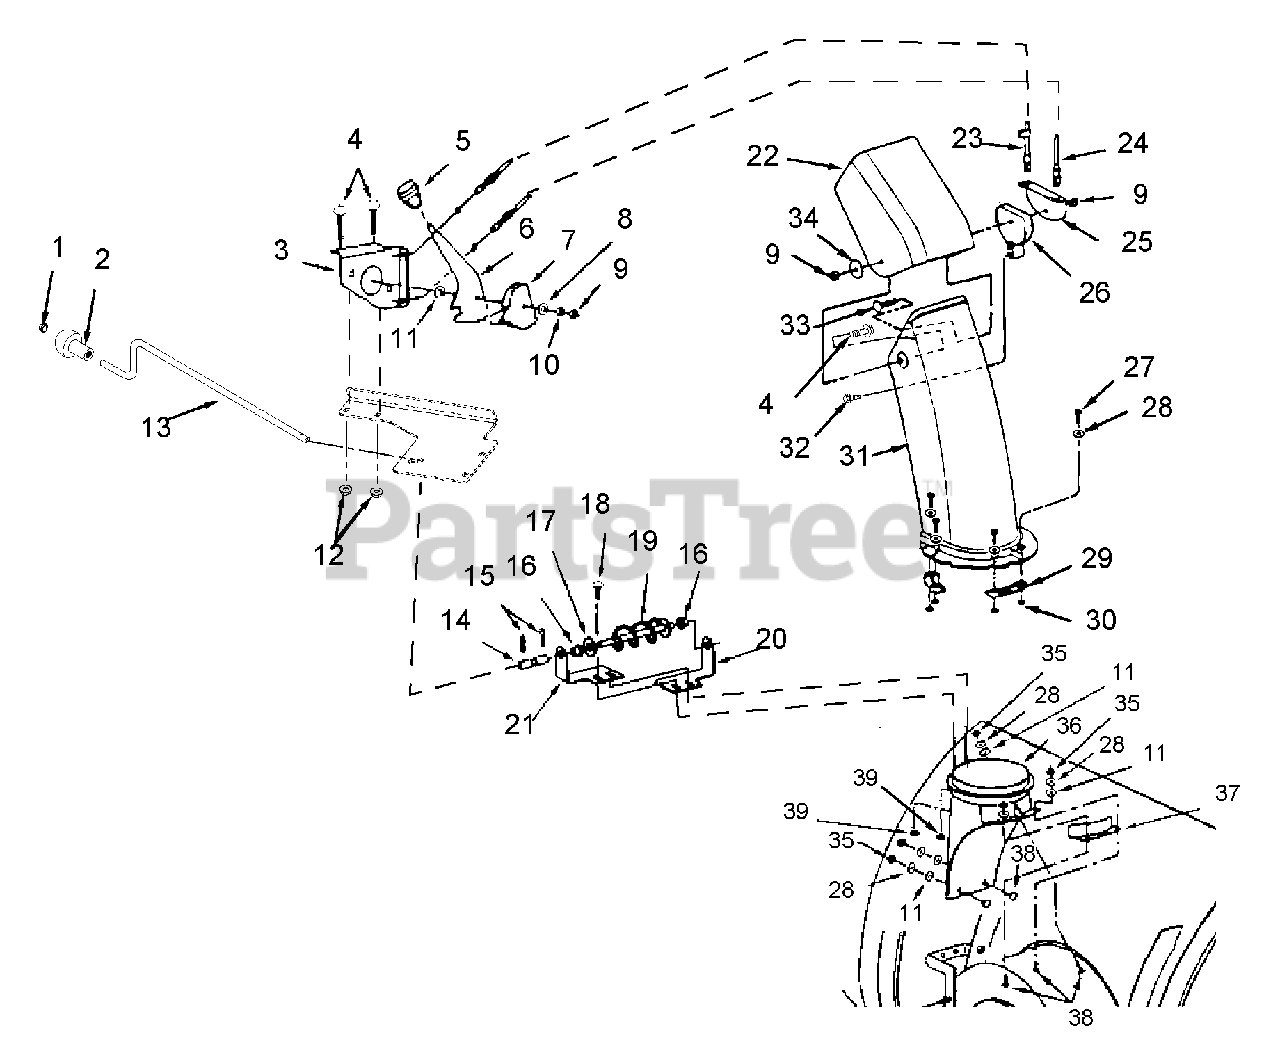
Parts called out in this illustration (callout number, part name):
1	CAP, 3/8 ROD YWZC
2	KNOB
3	Assembly, Chute Tilt Bracket
4	@BLT-RDHDSQNK .31-18X.75 G5YZ
5	Knob
6	Handle, Chute Tilt
7	Guide, Cable
8	@WSHR-FL-STL.344X.688X.065YWZC
9	@NUT-LK-CTR .31-18 YWZC
10	@WSHR-LK .31X.078 REG YWZC
11	WSHR-FL-NY .375X.75X.060
12	@NUT-LK-TOP-FLG .31-18 YWZC
13	CRANK, CHUTE
14	UNIVERSAL JOINT ASS'Y
15	PIN, SPRING CLIP
16	BUSHING,3/8" (AGRI-FAB)
17	@WSHR-FL-STL.406X.812X.065 YWZ
18	@BLT-RDHDSQNK .31-18X1.00 G5YZ
19	WORM,CHUTE CRANK
20	BKT,CHUTE CRANK FRONT
21	BKT,CHUTE CRANK REAR
22	Chute, Upper
23	Cable, Chute Control with Clip
24	Cable, Chute Control
25	Bracket, Cable
26	Guide, Cable
27	@BLT-HEX .25-20X1.00 GR5 YWZC
28	@WSHR-FL-STL.281X.62X.065 YWZC
29	Chute Keeper
30	@NUT-LK-CTR .25-20 YWZC
31	Chute, Lower
32	@SCR-MCH .25-20X.75 HWH YWZC
33	@BLT-RDHDSQNK .31-18X1.50 G5YZ
34	@WSHR-FL-STL.344X.688X.065YWZC
35	@NUT-LK-CTR .25-20 YWZC
36	Chute Adapter
37	Chute Reinforcement
38	@BLT-RDHDSQNK .25-20X.75 G5YZ
39	@NUT-LK-TOP-FLG .31-18 YWZC
